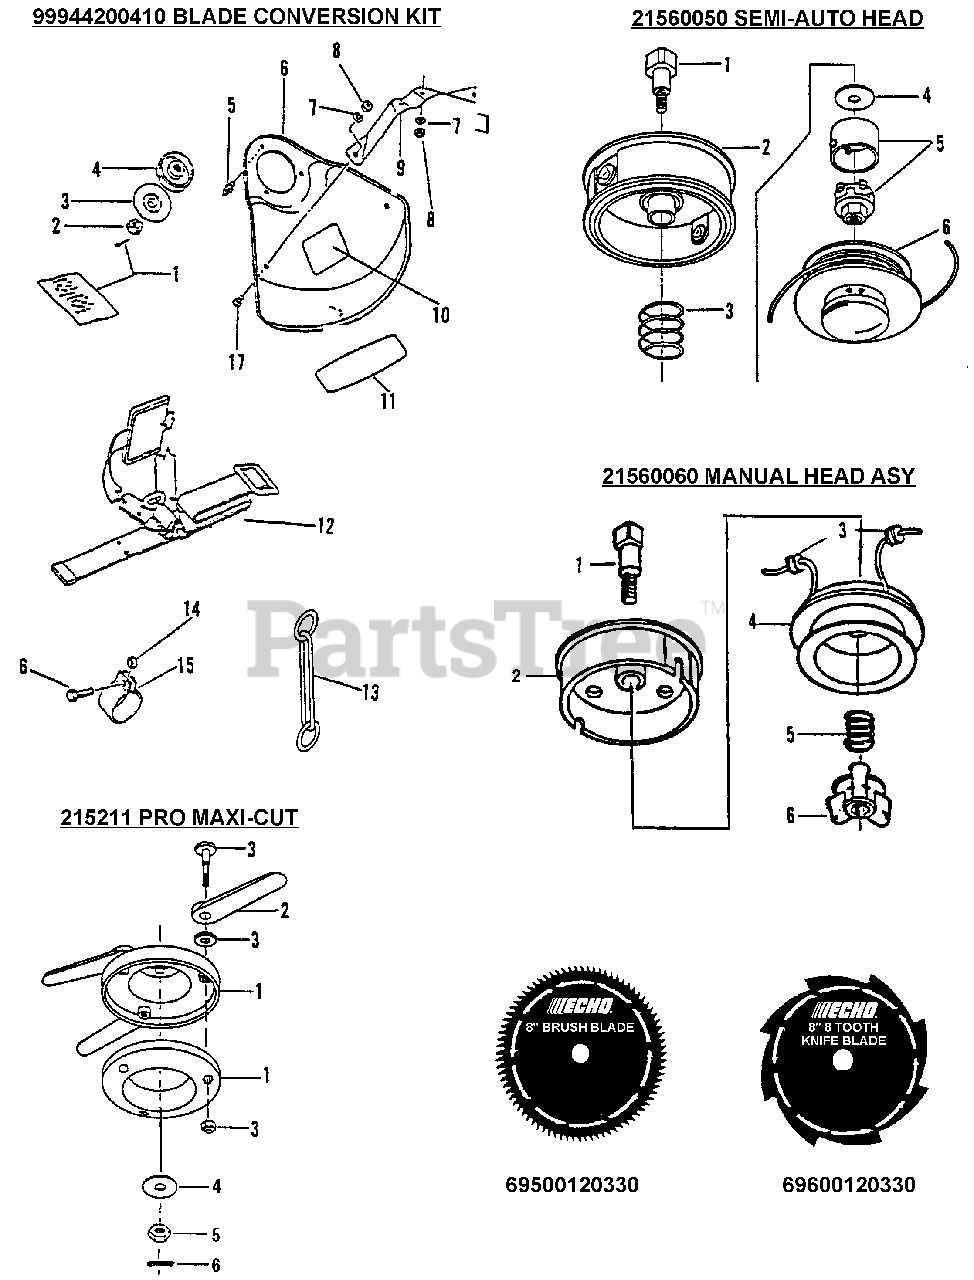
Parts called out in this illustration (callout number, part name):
1	PIN, COTTER 2×22
1	STUD, ARBOR M10×1.25 LH
2	HOUSING, SPOOL
2	HOUSING
2	BLADE SET
3	PLATE, ADAPTOR - LOWER
3	SPRING
3	EYELET
3	FASTENER SET
4	PLATE, ADAPTER - UPPER
4	WASHER
4	SPOOL
4	WASHER, MOUNTING
5	SCREW 5×10
5	CAM ASSY
5	SPRING
6	SHIELD
6	SPOOL
6	PIN, COTTER 2×22
7	WASHER, SPRING 5
8	NUT M5
9	BRACKET, SHIELD MOUNTING
10	LABEL - CAUTION
11	LABEL, ECHO
12	SHOULDER STRAP ASSY
13	HOOK
14	SPACER, GUARD
16	BOLT 5×18
17	SCREW 5×8
